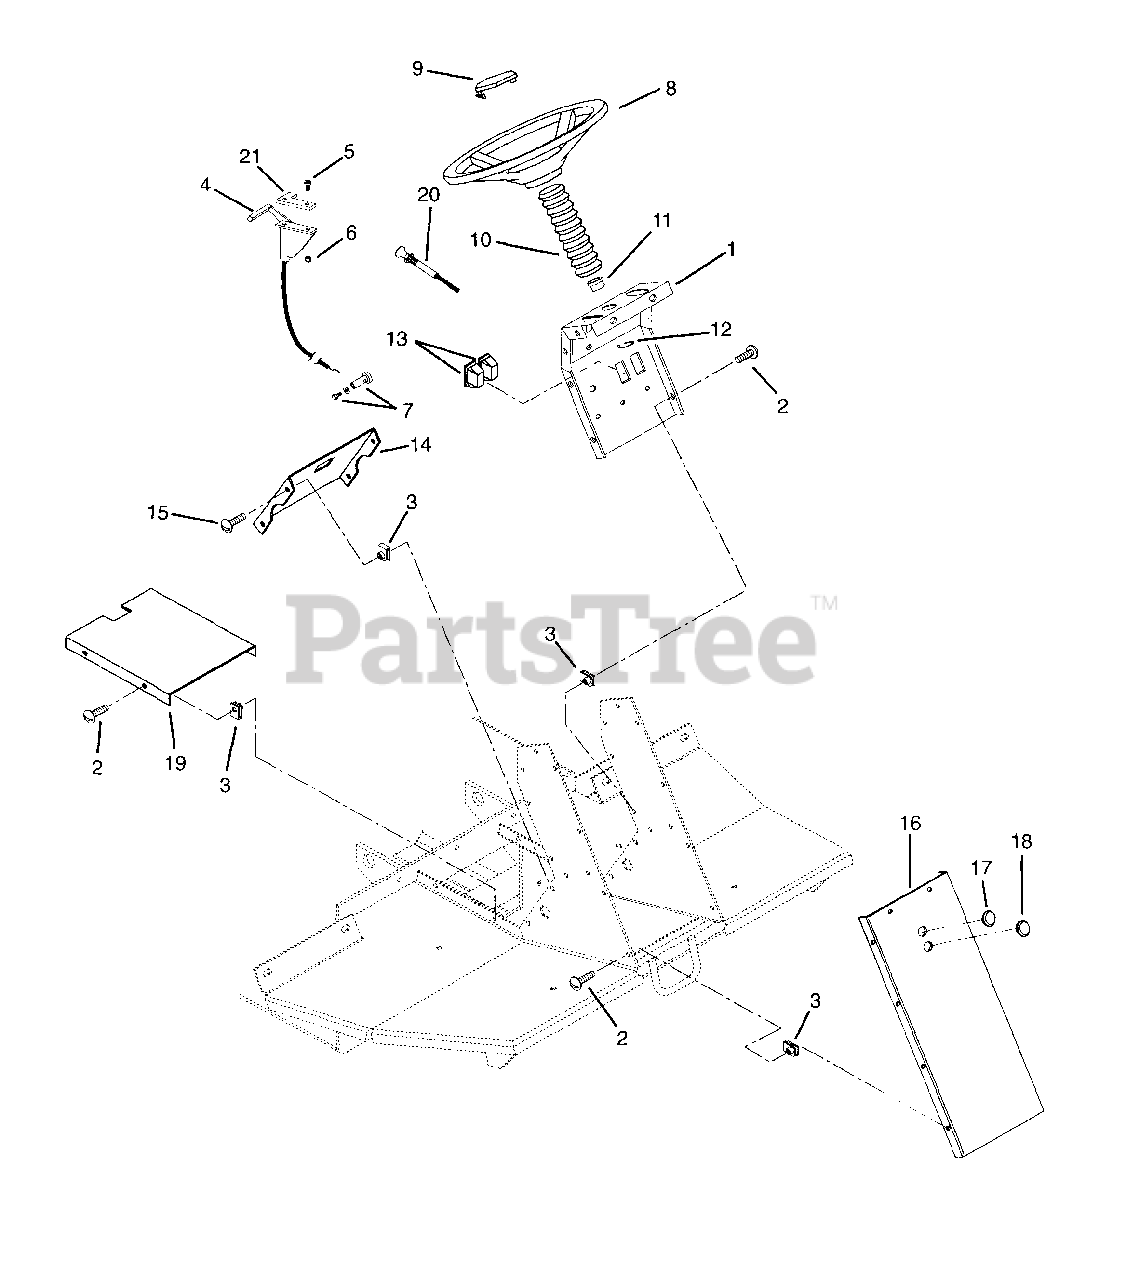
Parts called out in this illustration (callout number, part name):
1	Panel, Instrument
2	Screw-Machine .25-20 x .75
3	Nut-Retainer .25-20 x .56
4	Throttle Cable
5	Screw-Machine 10-24 x .50 Hex Washer Head
6	Nut-Jam 1/2-20 Grade 2
7	Swivel Assembly
8	Steering Wheel
9	Steering Wheel Cap
10	Steering Column Boot
11	Bushing-Flange .762 x 1.0 x .580 x 1.48
12	Ring-Retaining-External 1.310 x .050
13	Cover-Switch
14	Panel, Brake Lock
15	Screw-Machine .25-20 x .50
16	Panel, Front
17	Hole Plug
18	Plug, Hole
19	Panel, Access
20	Cable, Control
21	Stop, Throttle Cable
